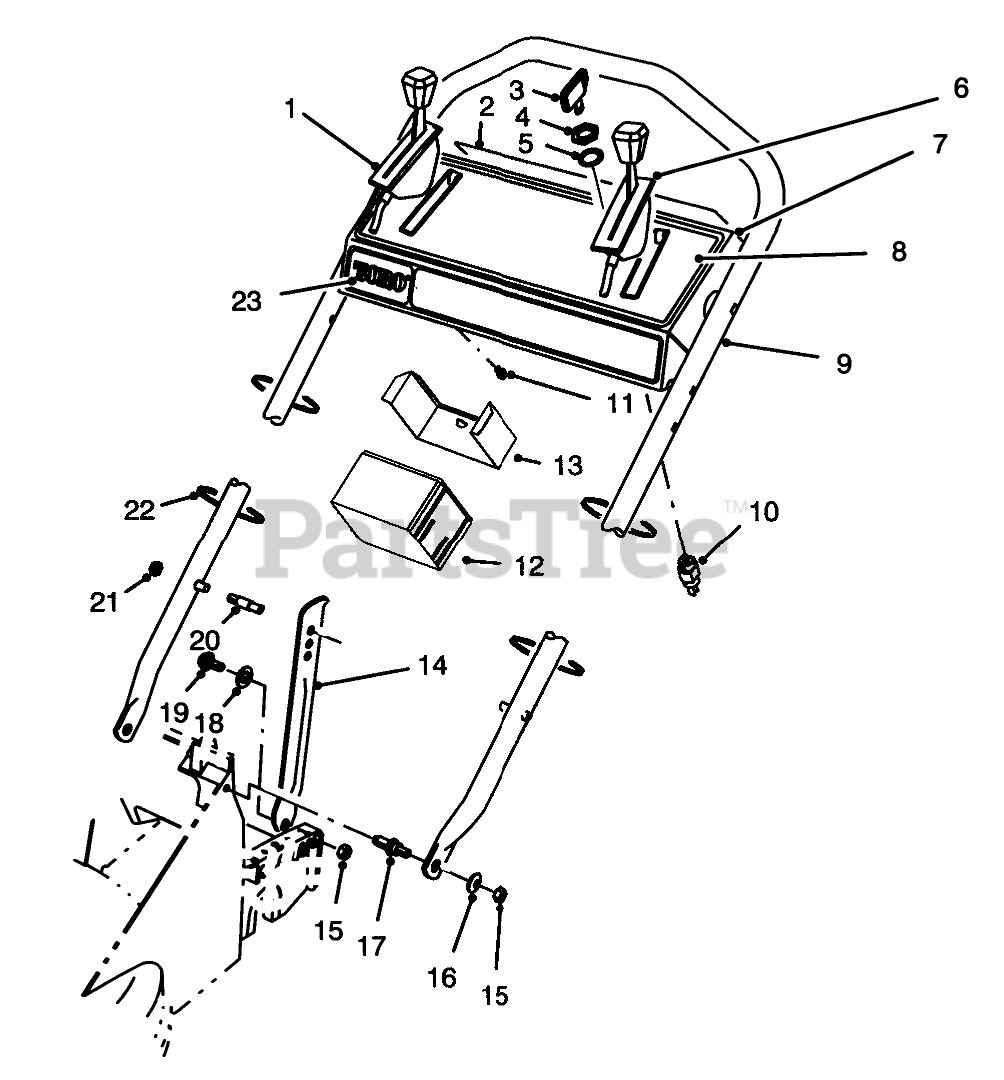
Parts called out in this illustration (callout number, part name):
1	GROUND SPEED CONTROL
2	DECAL - PANEL, REAR
3	KEY-IGNITION
4	NUT-HH
5	WASHER-TOOTH, INTERNAL
6	THROTTLE CONTROL
7	Panel-Control (Incl. Ref. #2, & 8)
8	DECAL - INSTRUCTION
9	UPPER HANDLE, PVC DIP
10	Switch-Starter (Incl. Ref. #4 & 5)
11	SCREW-HWHTF
12	BATTERY ASSEMBLY
13	Retainer-Battery
14	HANDLE LATCH
15	NUT-LOCK, NI
16	WASHER-PLAIN
17	SCREW - SHOULDER STUD
18	NYLON WASHER
19	SCREW-SHOULDER
20	HANDLE PIN
21	NUT-LOCK, NI
22	TIE-CABLE
23	DECAL - KEY LECTRIC
